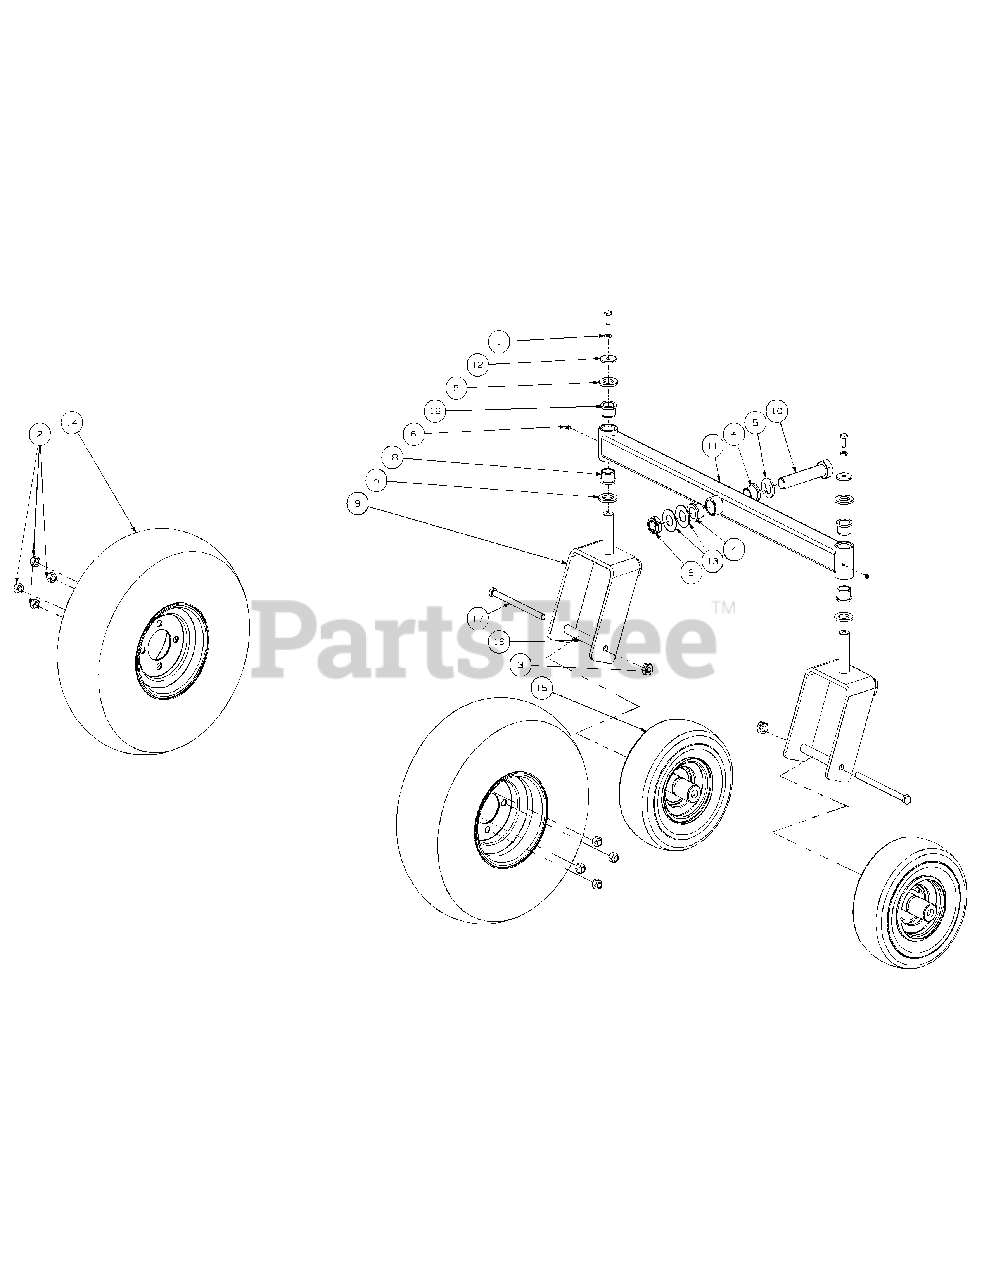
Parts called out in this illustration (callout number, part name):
1	Lock Washer, 3/8 Zinc
2	Lug Nut, 1/2-20
3	Nut, 1/2-20, Center Lock
4	Flange Bearing, 1.013 ID
5	Washer Special
6	Grease Fitting, 1/4-28 x 3/16
7	Hex Cap Screw, 3/8-16 x .88
8	Nut Jam, 1.0-14, Nylon Insert
9	Castor Wheel Mounting Bracket
10	Hex Cap Screw, 1-14 x 5.0
11	Front Axle Assembly
12	Flat Washer, .390 x 1.5 x .134
13	Flat Washer, 1.00 ID x 2.25 OD x ,075
14	Wheel Assembly, 20 x 8-10 NHS
15	Front Wheel Assembly
16	Wheel Spacer
17	Hex Cap Screw, 1/2-20 x 7.25
18	Flange Bearing, 1.0 ID
